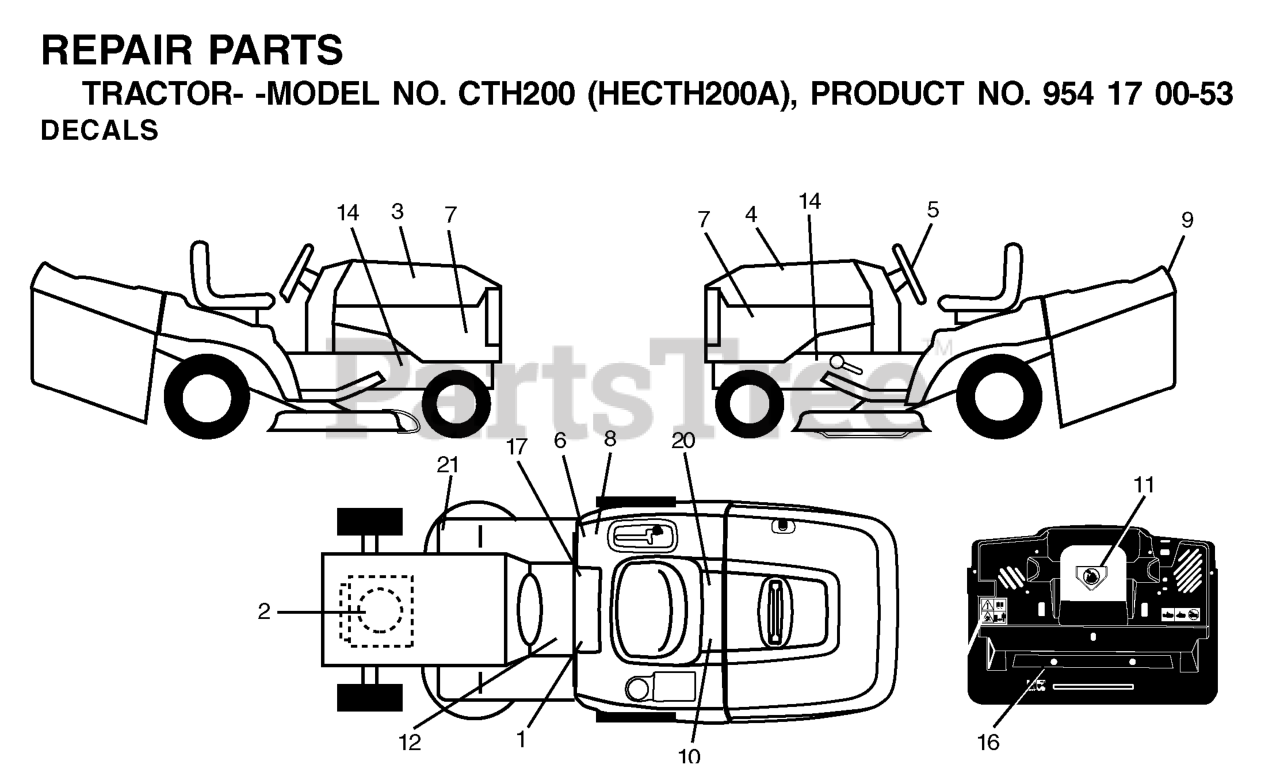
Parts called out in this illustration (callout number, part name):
1	DECAL READ OWNER'S MAN SYMS
5	DECAL.WHEEL.STEERING.HUSQ.PERM
6	DECAL CERTIFICATION
7	DECAL PNL SIDE
8	DECAL EUROPE STANDARD CE
9	DECAL FENDER HUSQ
10	DECAL BTRY SYMBOLS
11	DECAL MOWER CUT/FINGER
12	DECAL
16	DECAL
17	DECAL PARK BRAKE
20	DECAL.BYPASS.FENDER.CRD.LT.YT
